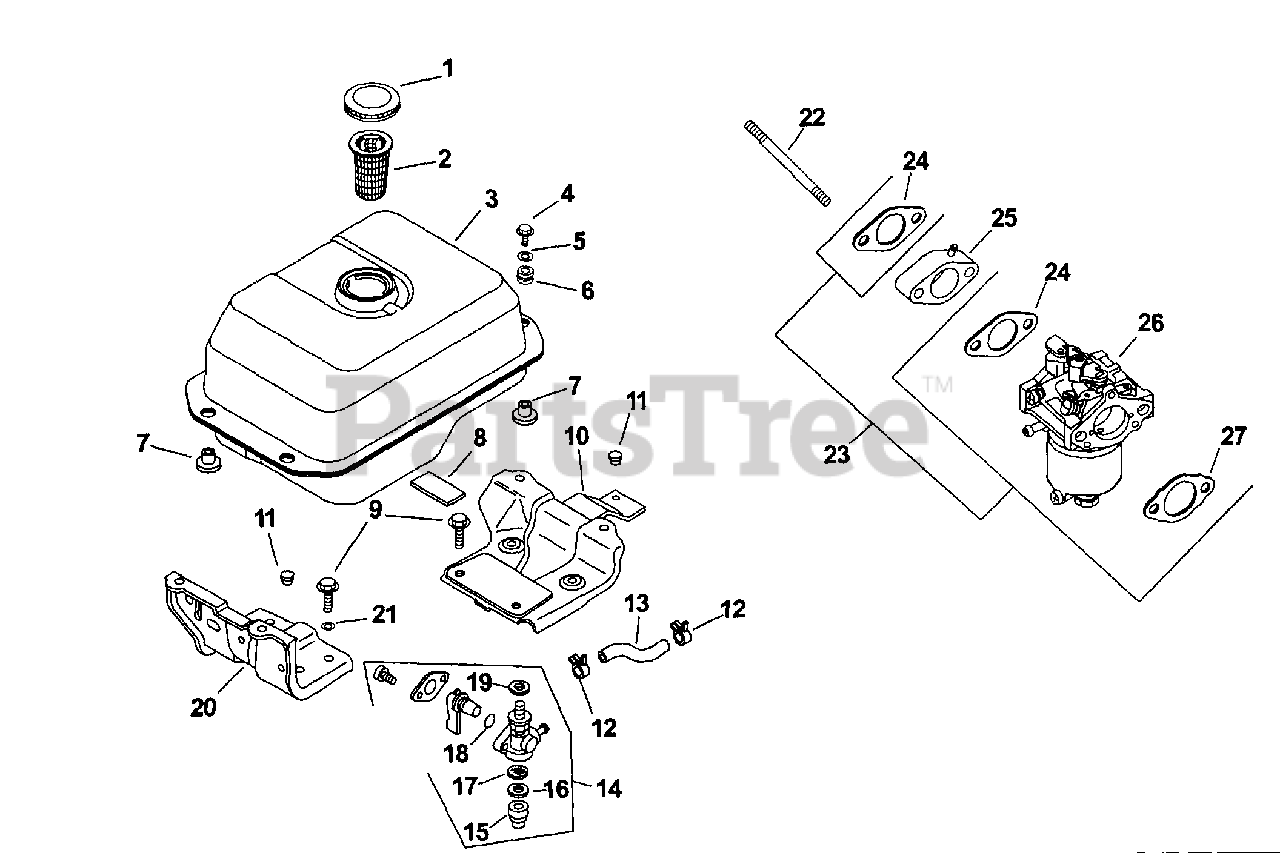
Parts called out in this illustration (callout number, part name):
9	SCREW, FLOAT BOWL
23	KIT, CARBURETOR W/GASKET
24	GASKET, INTAKE
25	MANIFOLD, INTAKE
